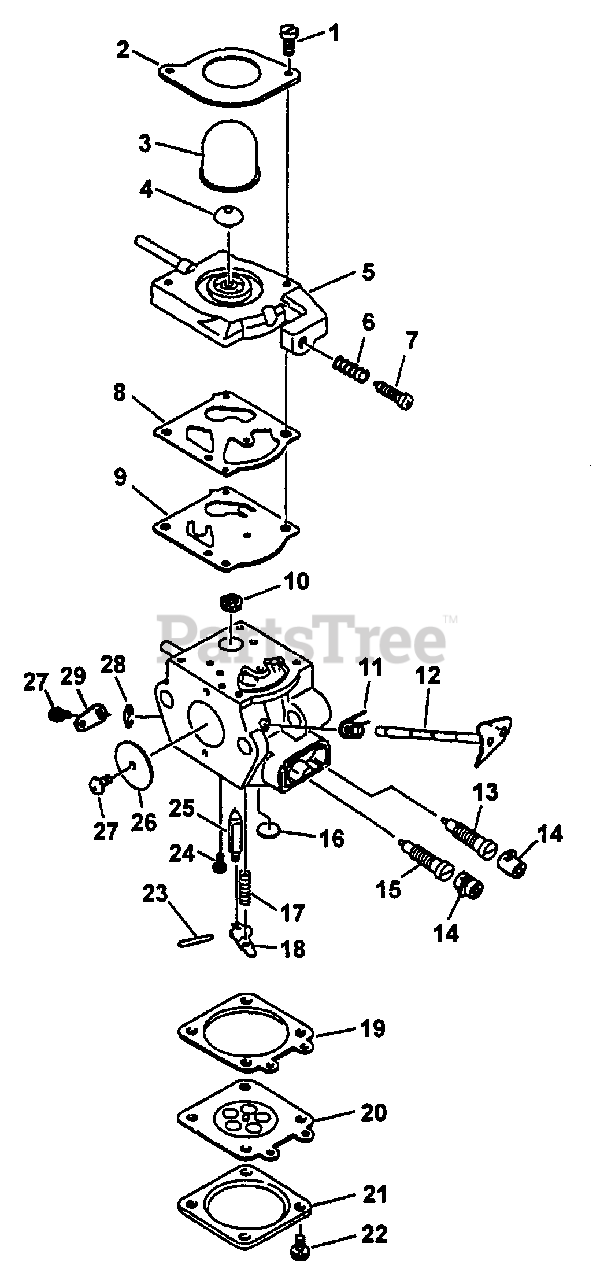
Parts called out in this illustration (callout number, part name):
1	SCREW, PUMP COVER
2	RETAINER, PURGE BULB
3	BULB, PURGE
4	VALVE, CHECK
5	COVER, PUMP
6	SPRING, IDLE ADJUST
7	SCREW, IDLE ADJUST
8	GASKET, PURGE
9	DIAPHRAGM, PURGE
10	REPAIR KIT
11	SPRING, THROTTLE RETURN
12	SHAFT, THROTTLE
13	NEEDLE - HIGH SPEED
14	CAP, LIMITER
15	NEEDLE - LOW SPEED
16	PLUG, WELCH
17	SPRING, METERING LEVER
18	LEVER, METERING
19	GASKET, METERING
20	DIAPHRAGM, METERING
21	COVER, METERING
22	SCREW, METERING COVER
23	PIN, METERING LEVER
24	SCREW, METERING LEVER PIN
25	VALVE, INLET NEEDLE
26	VALVE, THROTTLE
28	RING, RETAINING
29	LEVER, THROTTLE
